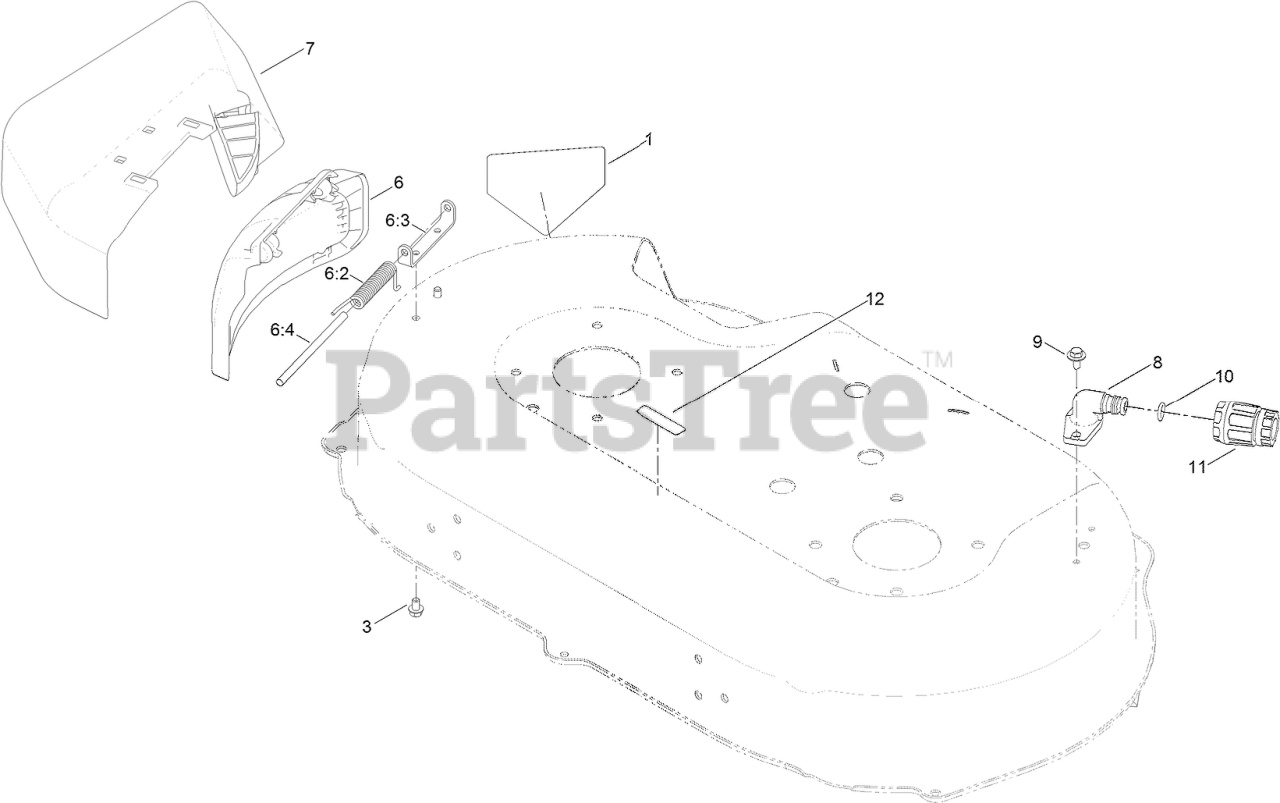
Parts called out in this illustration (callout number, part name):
1	DECAL-DANGER
3	SCREW-HWH
6	SIDE DEFLECTOR SERVICE ASM
6:2	SPRING-TORSION, COVER
6:3	BRACKET-COVER
6:4	ROD-COVER
7	SIDE DISCHARGE CHUTE ASM
8	FITTING-WASHOUT
9	SCREW-HHFTF
10	O-RING
11	CONNECTOR-HOSE
12	DECAL-WARNING
